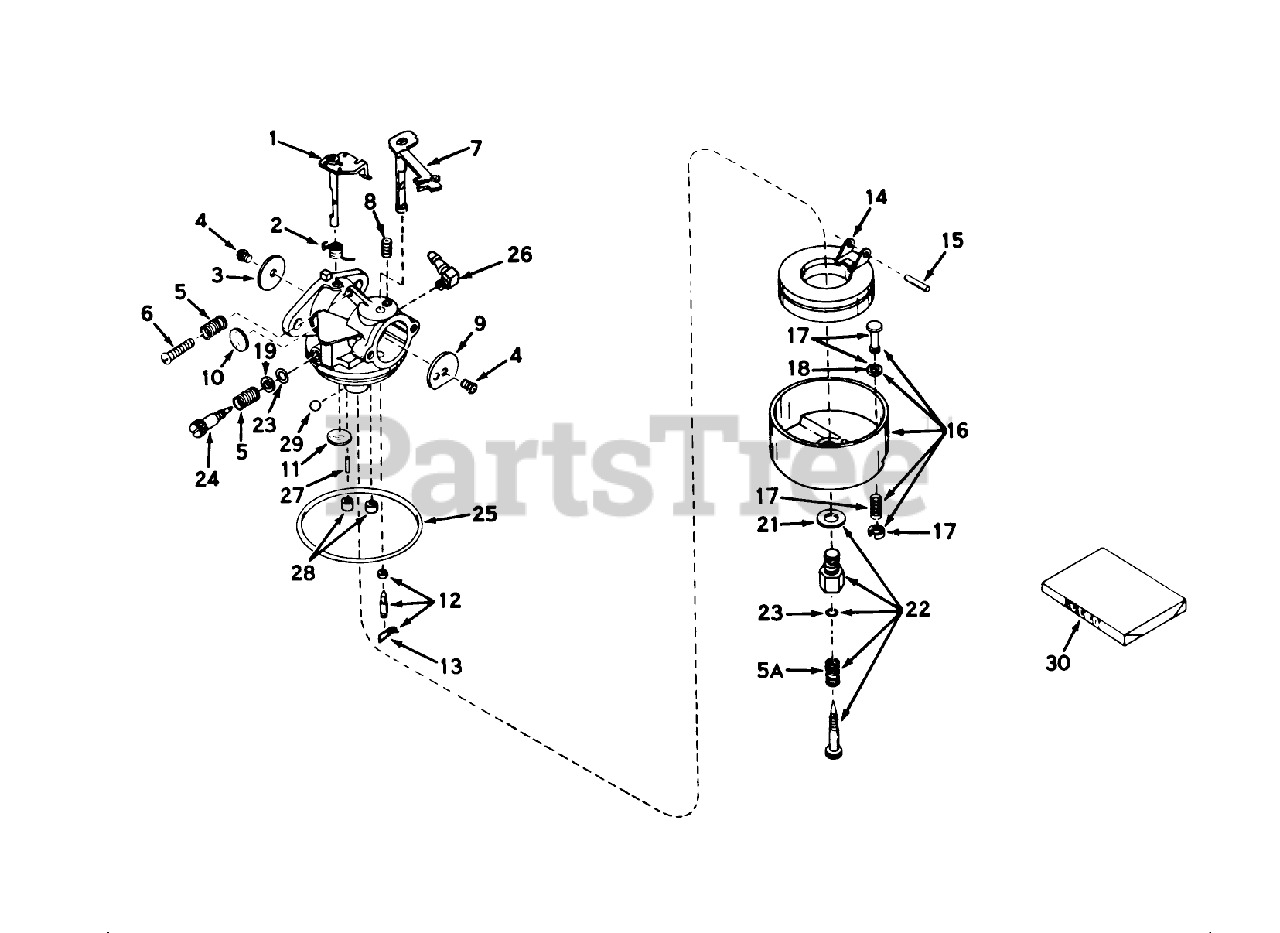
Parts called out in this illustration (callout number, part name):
1	Shaft Lever Assy.
2	Spring, Throtte Return
3	Shutter-Throttle
4	Screw-Shutter
5	Spring-Tension
5A	Spring
6	Screw-Throttle Crack Screw / Idle Speed
7	Shaft Lever Assy., Choke
8	Spring-Positioning, Choke
10	Plug-Welch, Idle Mixture Well
11	Plug-Welch, Atmospheric Vent
12	Inlet Needle, Seat Clip Assy. (Incl. No. 13)
13	Clip-Spring
14	Float,Carburetor
15	Shaft-Float
16	Bowl Drain Assy., Float (Incl. No. 17)
17	Bowl Drain ASM
18	Gasket-Plunger, Drain
19	Washer
21	Washer-Bowl Nut
22	Adjustment Screw Assy., Main (Incl. Nos. 5A, 21 23)
23	ORing
24	Screw, Idle Adj.
25	O Ring-Bowl, Float
26	Fitting Fuel Inlet
28	Plug, Cup
29	BalI, Steel
30	Repair Kit (Incl. items marked *)
